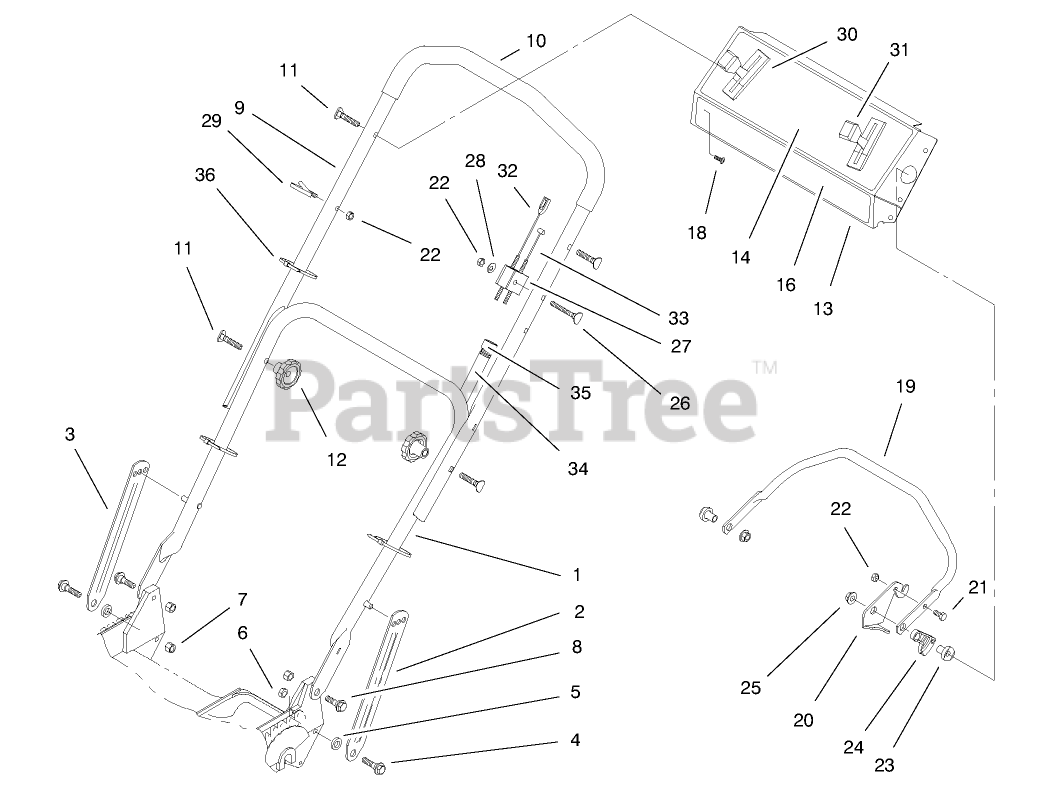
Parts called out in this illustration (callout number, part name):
4	SCREW-SHOULDER
5	SPACER
6	NUT-LOCK, NI
7	Nut-Lock
8	SCREW-SHOULDER
11	SCREW-HANDLE
16	DECAL - CONSOLE
18	SCREW-TAP
21	SCREW-HH
22	NUT-LOCK, NI
23	SPACER-SUPPORT
24	LEVER-TRACTION
26	SCREW-HANDLE
27	SUPPORT-CABLE
28	WASHER-FLAT
29	GUIDE-ROPE
30	CONTROL-SPEED, GROUND
31	THROTTLE CONTROL
32	BRAKE CONTROL
33	CABLE-TRACTION
35	FITTING-RING
36	TIE-CABLE
